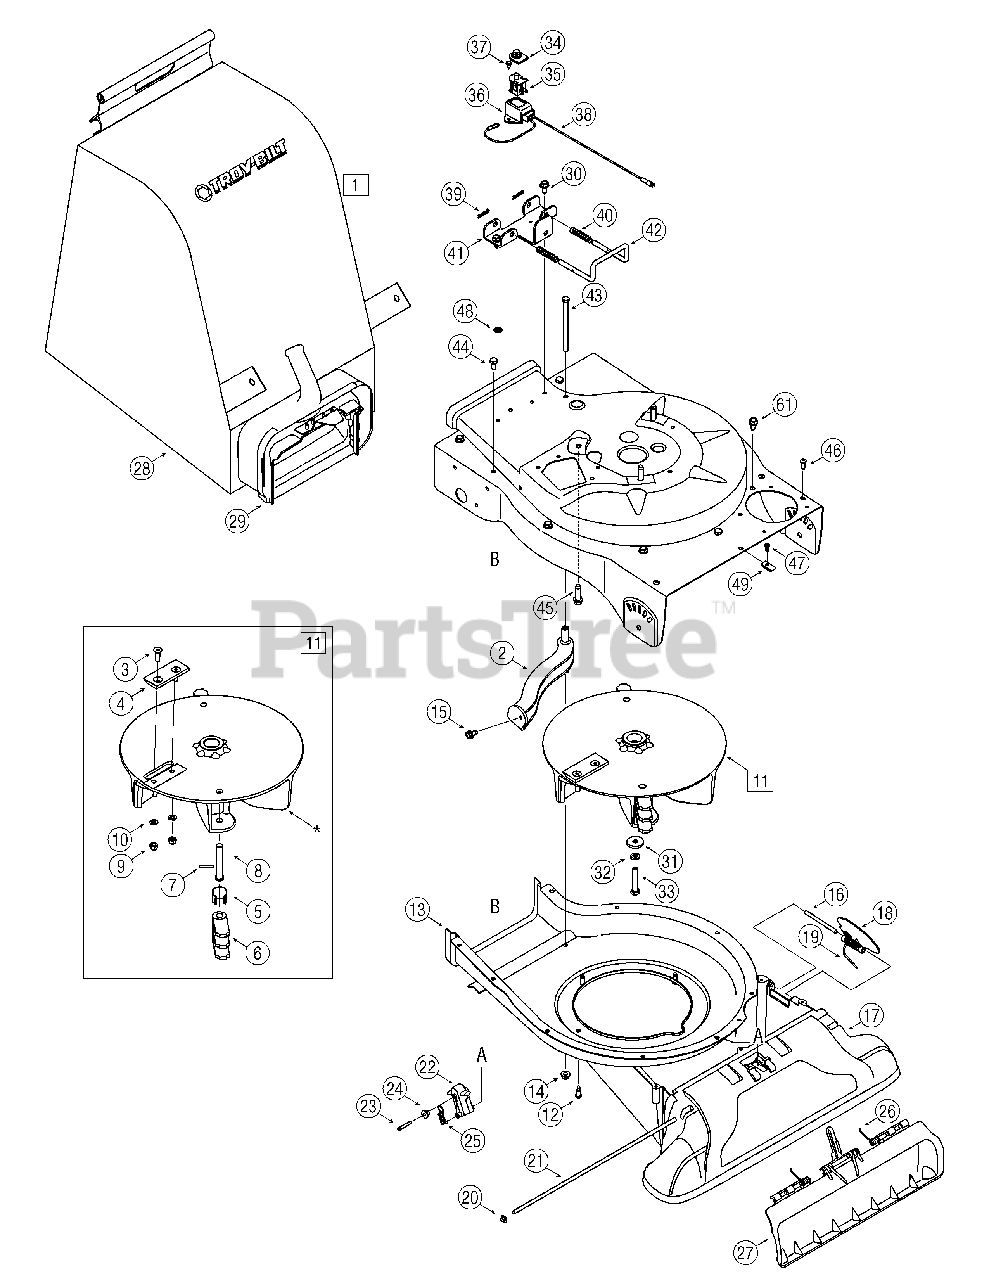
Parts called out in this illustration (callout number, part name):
1	Bag Assembly
3	Hex Screw 5/16-24 x 1.0
4	Chipper Blade
7	Spiral Pin
8	Clevis Pin
9	Lock Nut, 5/16-24
10	Lock Washer, 5/16
11	Impeller Assembly (Incl. Ref.# 3 - 10)
12	Shoulder Screw, #12-24 x.30 x .46
14	Flange Lock Nut 5/16-18
15	Screw, 5/16-18 x.500
17	Nozzle
18	Base Adapter Door
19	Torsion Spring
20	Cap Speed Nut 1/4
21	Pivot Rod
22	Nozzle Door Lever
23	Hex Screw, #8-18 x 1.25
24	Shoulder Spacer
25	Extension Spring
26	Nozzle Door Torsion Spring
27	Nozzle Door
28	Bag, with Troy Logo
28	Bag, Black no logo
29	Chute Assembly
30	Hex Index Screw, 5/16-12 x.750
31	Flat Washer.375 ID x 1.25 OD
32	Lock Washer 3/8
33	Hex Cap Screw 3/8-24 x 2.0
34	Switch Cover
35	Safety Switch
36	Safety Switch Cover
37	Hex Washer Screw #10-16 x.50
38	Wire Harness
39	Cotter Pin
40	Compression Spring
43	Hex Cap Screw 5/16-18 x 4.5
44	Hex Cap Screw 5/16-18 x.625
45	Hex Washer Screw 3/8-16 x 1
46	Screw, #12-16 x.750
47	Screw #10 - 16 x.500
48	External L-Washer 5/16
49	Speed Nut
